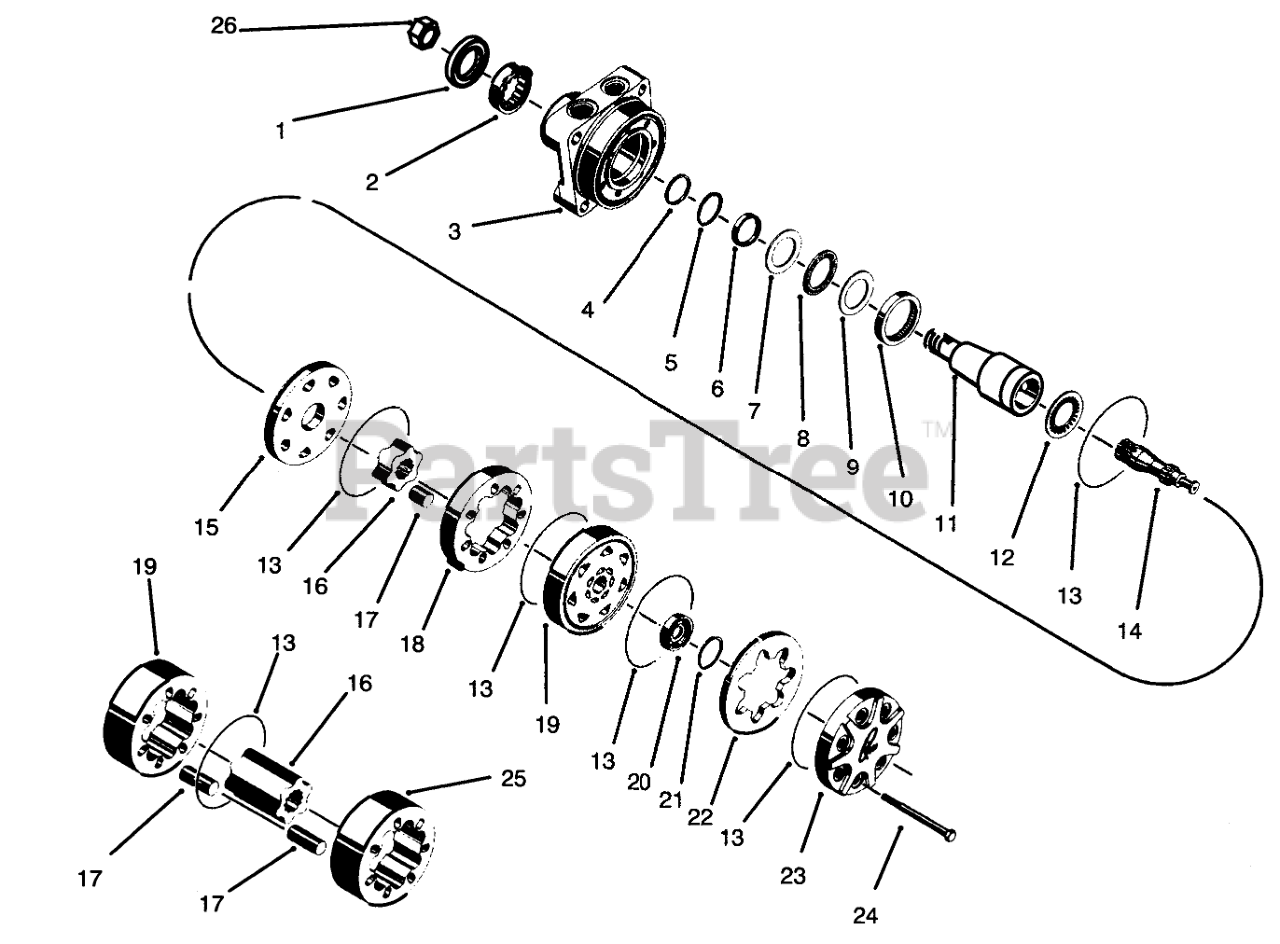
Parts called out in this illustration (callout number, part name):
1	Seal ASM
2	Bearing
3	Housing
4	Washer-Back Up
5	Washer-Back Up
6	Seal ASM
7	Washer-Thrust
8	Bearing-Thrust
9	Washer-Thrust
10	Bearing-Inner
11	Coupling-Shaft
12	Bearing-Thrust
13	"O"Ring
14	Link-Drive
15	Plate Wear
16	Rotor
17	Vane
18	Stator
19	Manifold
20	Commutator
21	Seal-Commutator
22	Commutator-Ring
23	Cover-End
24	Special
25	Stator Half
26	NUT-MOTOR, WHEEL
